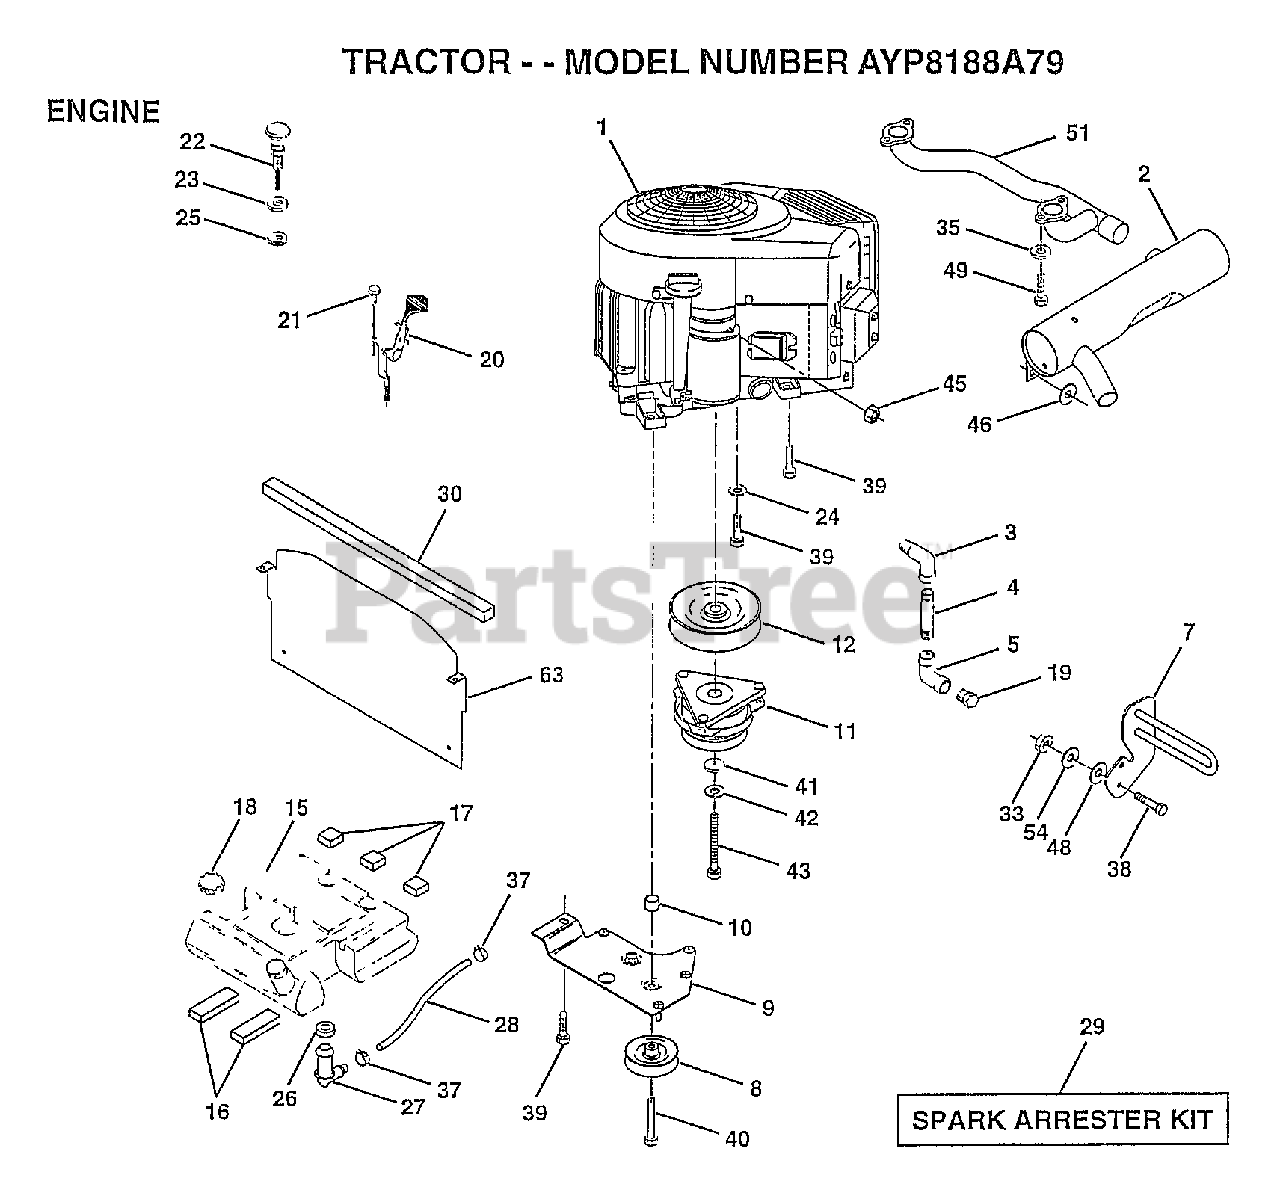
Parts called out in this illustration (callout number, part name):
3	STREET ELBOW LT
4	PIPE NIPPLE
5	ELBOW
7	GUARD.MUFFLER.ASM
9	KEEPER ASM BELT
10	BUSHING.
12	PULLEY.ENGINE.VGT
15	TANK FUEL REAR
16	PAD IDLER TI
17	PAD-SPACER LT
18	CAP ASM FUEL
19	PLUG T
21	SCREW LT
23	WASHER
24	LOCKWASHER
25	"NUT,KEPS 3/8-24IM"
26	BUSHING OUTLET T
27	STEM.TANK.FUEL
29	SPARK ARREST KIT
30	FOAM-STRIP LT
33	NUT
35	LOCKWASHER
37	HOSE CLAMP
38	"BOLT,HEX"
39	SCREW LT
40	SCREW.3/8-16X3.25
41	WASHER
42	LOCKWASHER
43	BOLT.7/16-20X4.25
45	NUT
46	WASHER HYT
48	WASHER T
49	BOLT.HD.SOCKET.
51	PIPE.EXHAUST.B&S
54	WASHER
63	SHIELD.HEAT.VGT.
